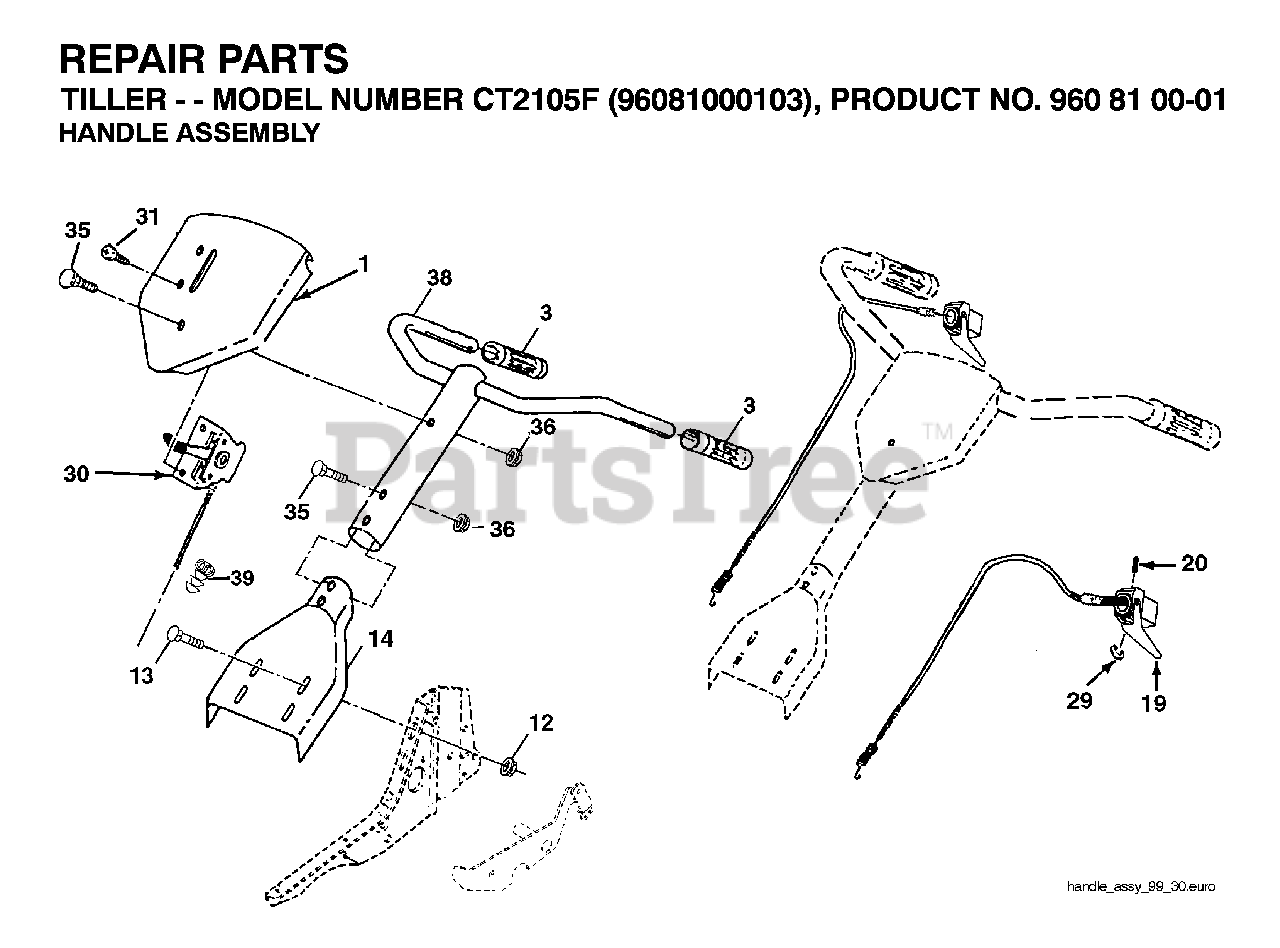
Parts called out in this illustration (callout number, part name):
12	NUT
13	BOLT.RH.SQNK.5/16
14	PANEL ASM. POLE
20	PIN, PIVOT
29	RETAINING RING
31	SCREW
35	BOLT.5/16-18X2.5
36	LOCKNUT-FLANGE 5/16-18
39	CLIP.ROUTING DUAL
